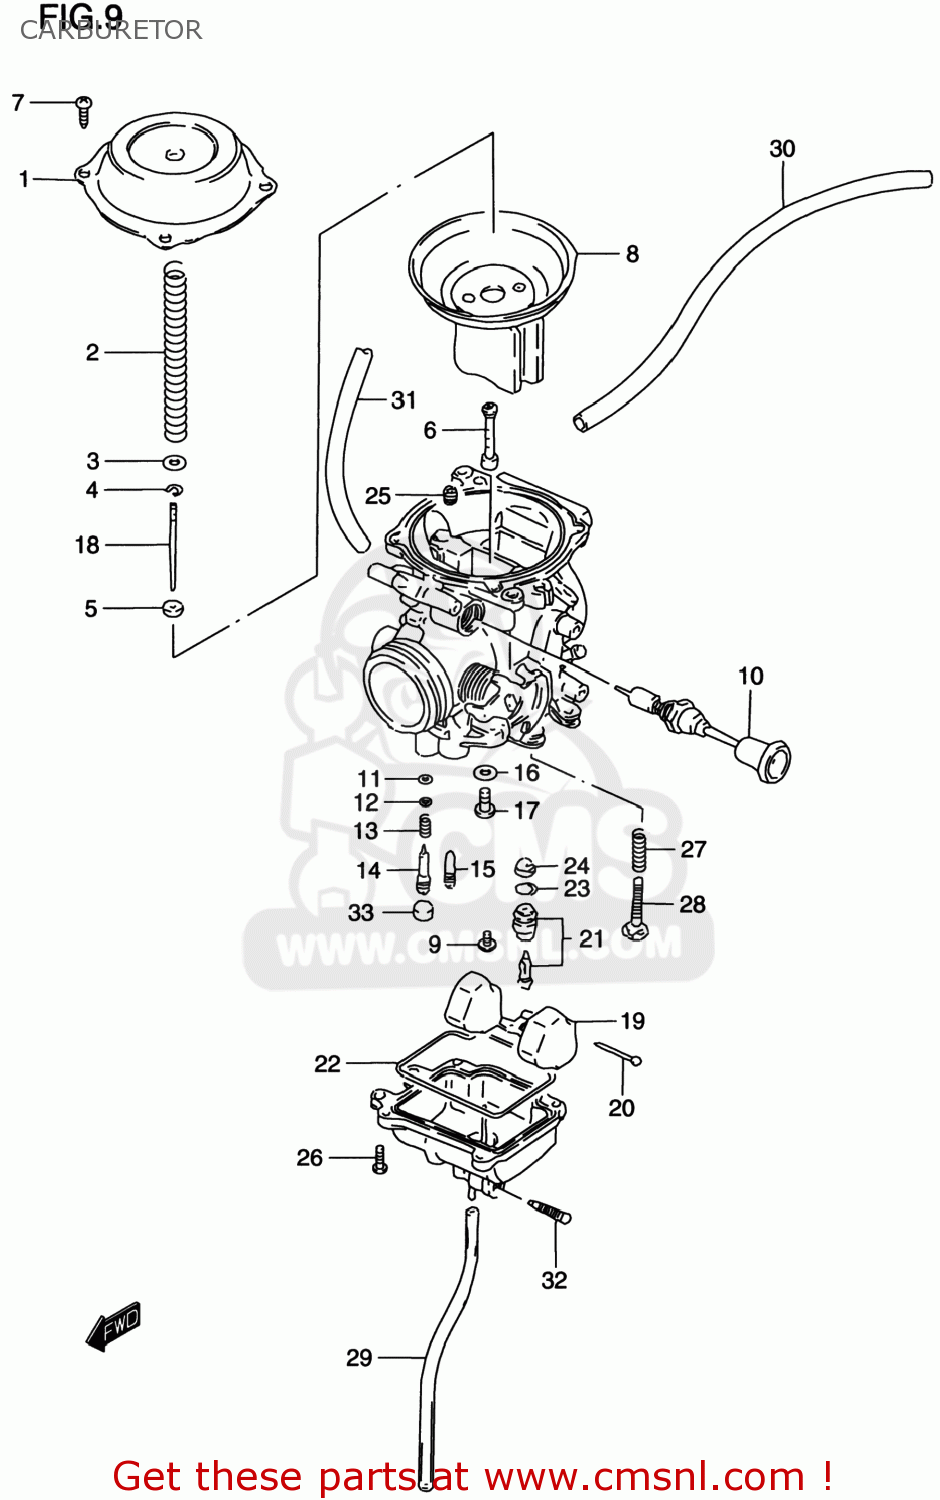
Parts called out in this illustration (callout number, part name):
1	COVER,DIAPHRAGM
2	SPRING
3	RING
4	CLIP
5	RING
6	JET,NEEDLE(P-5)
7	SCREW
8	DIAPHRAGM ASSY
9	SCREW
10	PLUNGER ASSY
11	O RING,PILOT AIR SCREW
12	WASHER
13	SPRING
14	SCREW,PILOT
15	JET(40)
16	WASHER
17	JET,MAIN(125)
18	NEEDLE,JET
19	FLOAT
20	PIN,FLOAT
21	VALVE ASSY,NEEDLE
22	O RING,FLOAT CHAMBER
23	O-RING,NEEDLE VALVE
24	FILTER
25	JET,AIR(135)
26	SCREW
27	SPRING,THROTTLE SCREW
28	ADJUSTER
29	HOSE(3X5X650)
30	HOSE(5X8.2X600)
31	HOSE(4.5X8.5X600)
32	SCREW,DRAIN
33	PLUG
